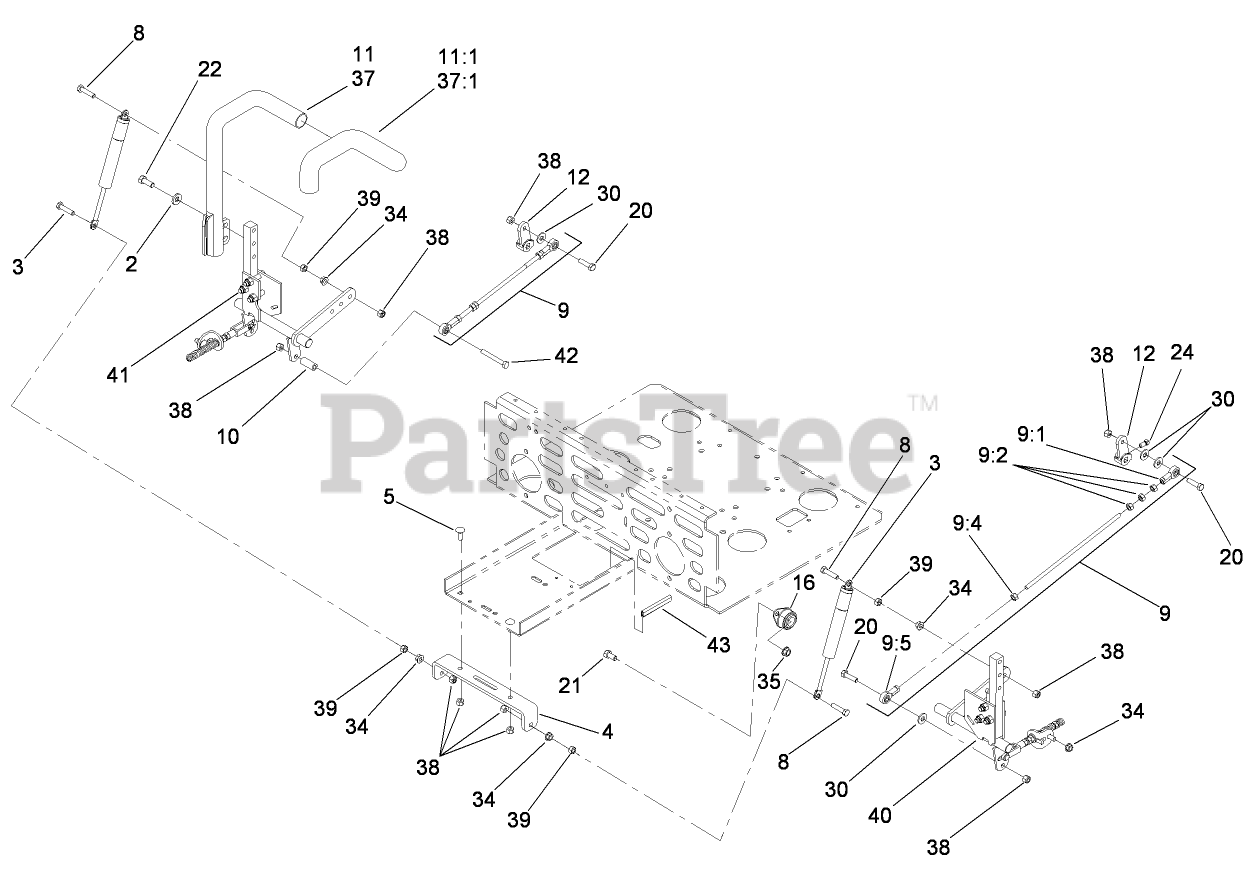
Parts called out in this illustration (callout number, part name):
2	WASHER-BELLEVILLE
3	DAMPER-CONTROL, MOTION
4	BRACKET-MOUNT, DAMPER
5	BOLT-CARR
8	SCREW-HH
9	Tracking Rod ASM
9:1	BALLJOINT-RH
9:2	NUT-HEX
9:5	BALLJOINT-LH
10	SPACER
11	LH LEVER ASM
11:1	Grip-Control, Motion
12	ARM-CONTROL, PUMP
16	BEARING-FLANGE, SIDE
20	SCREW-HH
21	SCREW-HH
22	SCREW-HH
24	SCREW-SET
30	WASHER-FLAT
34	NUT-HF
35	NUT-HHF, WHIZ
37	RH LEVER ASM
37:1	Grip-Control, Motion
38	NUT-LOCK, NI
39	NUT-HEX
40	LH MOTION CONTROL ASM
41	RH MOTION CONTROL ASM
42	SCREW-HH
43	STRIP-SEAL
